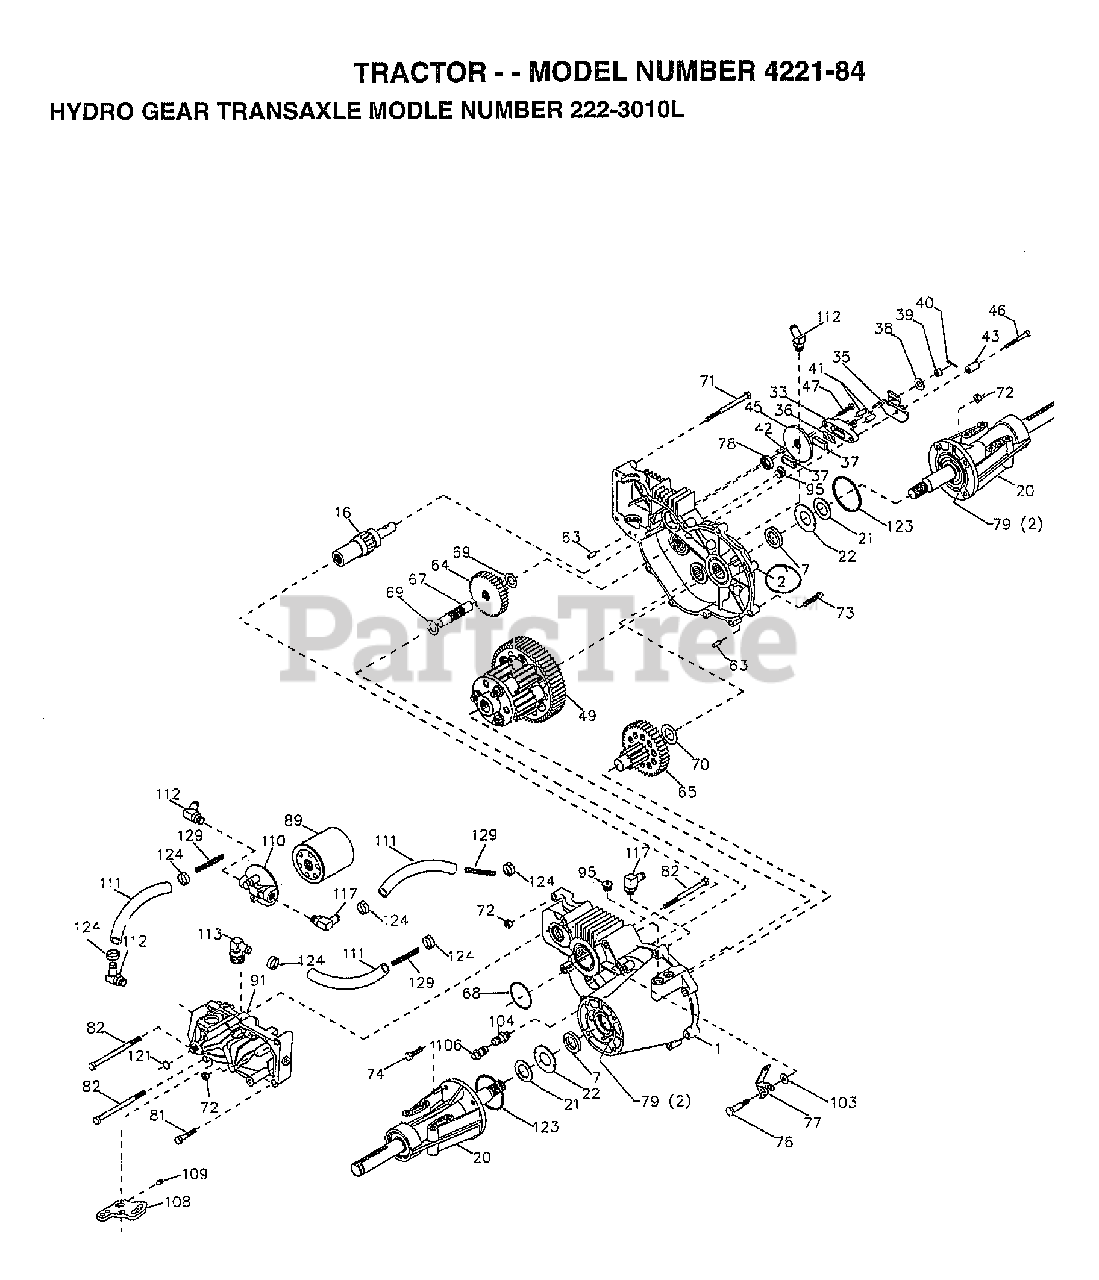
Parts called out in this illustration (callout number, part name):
1	ASSEMBLY,HOUSING LH
2	ASSEMBLY,HOUSING RH
7	SEAL.OIL.44782.HY
16	SHAFT BRAKE 62877
20	AXLE MTG 70087
21	WASHER 44805
22	WASHER 44806
33	YOKE.BRAKE.62589
35	ARM BRAKE 50214
36	PUCK PLATE 44134
37	PUCK BRAKE 44132
38	WASHER HYD 44130
41	PIN BRAKE 44127
42	KEY HI PRO 44143
43	SPACER 50259
45	DISC BRAKE 44090
46	BOLT 1/4-20 44276
47	BOLT 1/4-20 44433
49	DIFFRENTIAL.70251
63	PIN DOWL 44757
64	GEAR.14-38.44776
65	PINION DRIV 70051
67	SHAFT-44779
68	O RING 44781
69	WASHER 44795
70	WASHER 44794
71	BOLT 5/16 44827
72	LOCKNUT.43064
73	BOLT 5/16 44841
74	SCREW 5/16 45089
76	BOLT SHOULD 44785
77	ARM FREEWHL 44786
78	SEAL.OIL.44761
81	BOLT 5/16 43084
82	BOLT 5/16 44820
89	FILTER SPIN 50037
91	PUMP.BDU-10L-122
95	PLUG.9005110-5600
96	FITTING.SAE.50257
103	WASHER.50169
104	CAP.VENT.70109
106	O-RING.ASM.70110
108	ARM.CONTROL.45007
109	SCREW.SET.50018.
110	FILTER.HEAD.50207
111	HOSE.50632
112	FITTING.SAE.50604
113	FITTING.SAE.50592
117	FITTING.SAE.50589
123	O-RING.50405
124	CLAMP.50590
129	SPRING.LONG.50667
